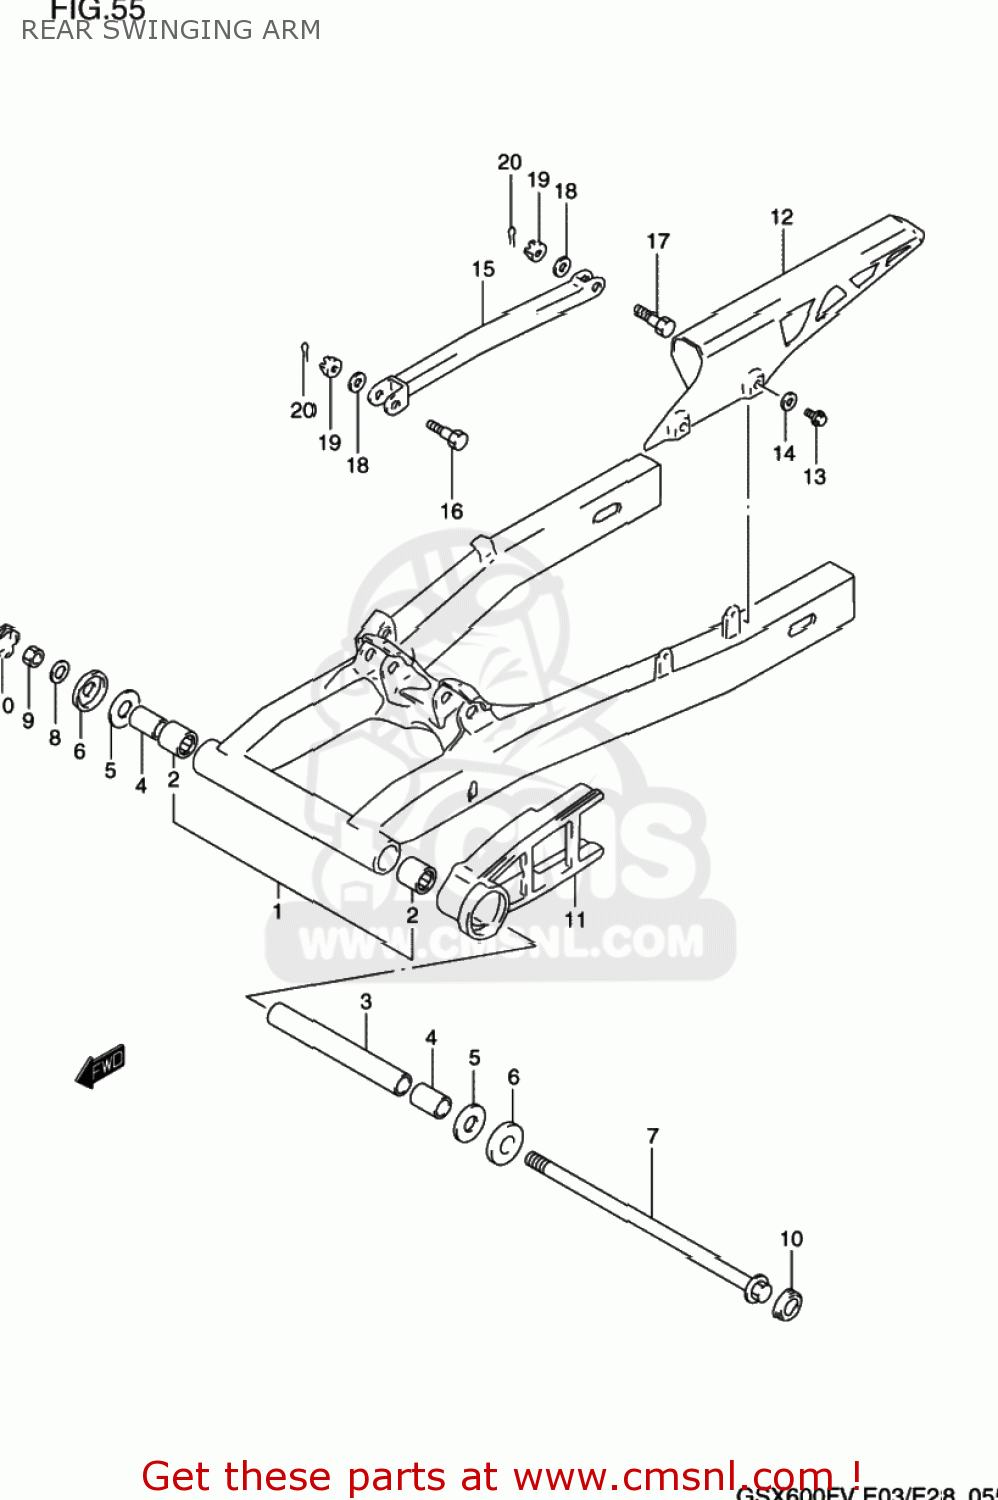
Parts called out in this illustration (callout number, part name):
1	SWINGINGARM ASSY,RR
2	BEARING(22X29X30)
3	SPACER,RR SWGARM PIVOT CTR
4	SPACER,RR SWGARM PIVOT
5	WASHER
6	CVR,RR SWGARM DUST SEAL(OD:40)
7	SHAFT,REAR SWING ARM PIVOT
8	WASHER(14X27X3)
9	NUT
10	CAP,SWINGINGARM PIVOT
11	BUFFER,CHAIN TOUCH DEFENSE
12	CASE,CHAIN
13	SCREW 6X12
14	WASHER
15	TORQUE LINK,REAR
16	BOLT(10X41)
17	BOLT(10X35)
18	WASHER (10X18X3.2)
19	NUT
20	PIN 20X20
